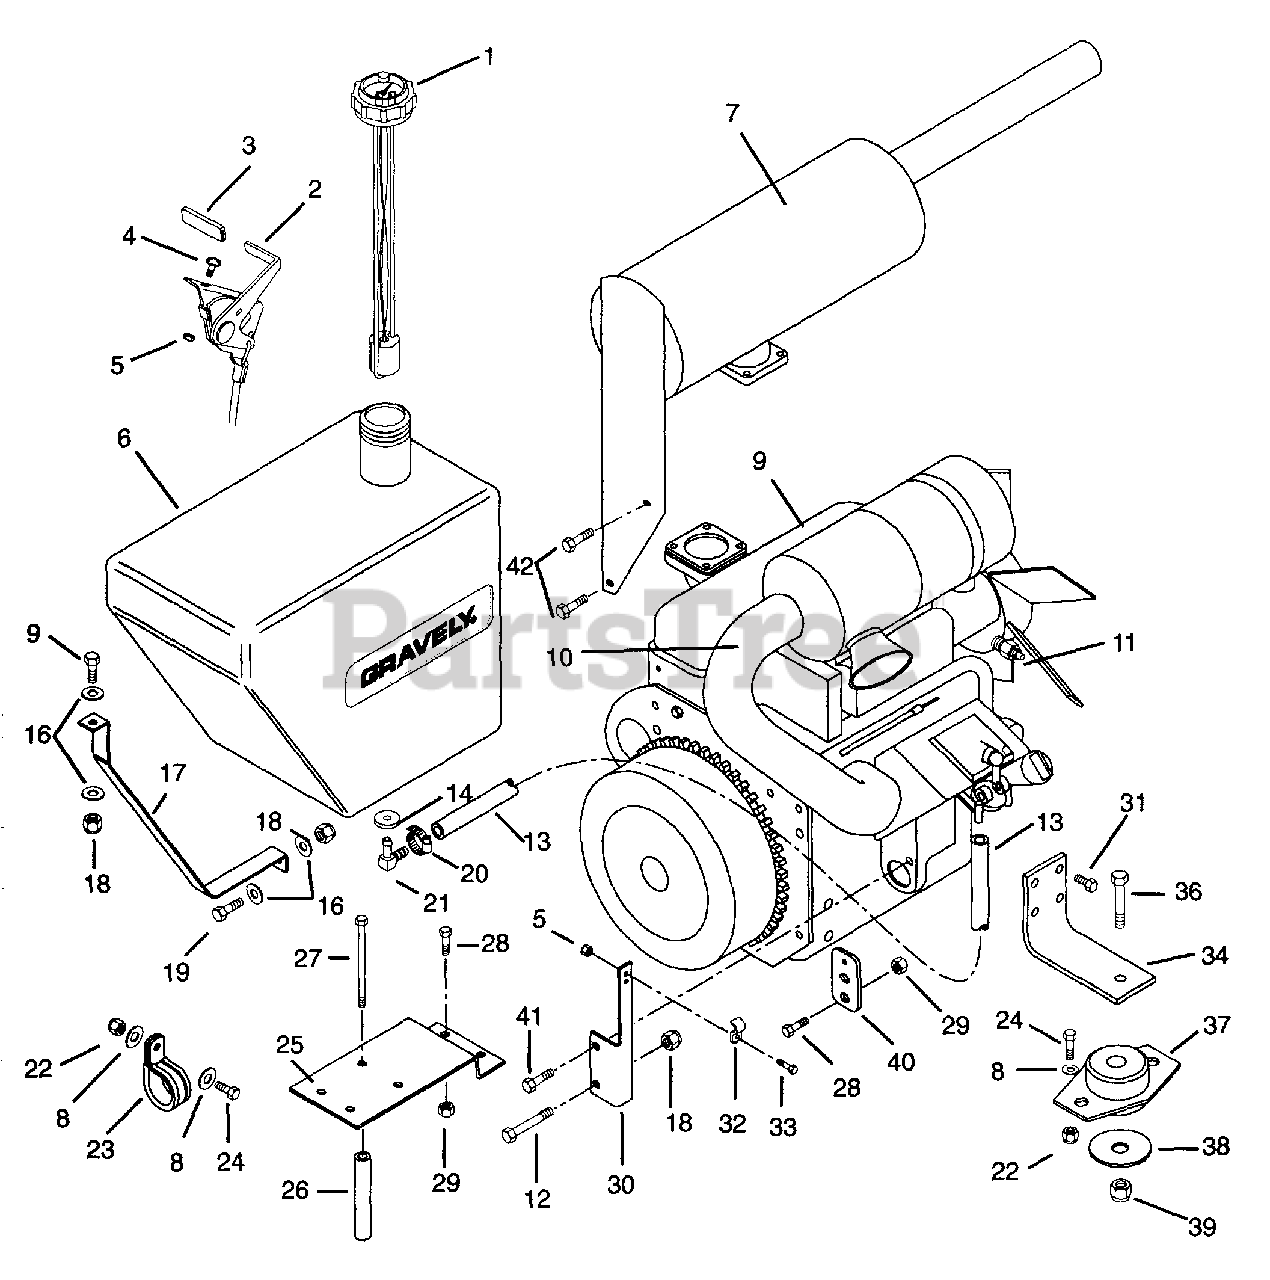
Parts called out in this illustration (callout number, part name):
1	Gauge, Fuel
2	Throttle Cable Assembly
4	Screw-Machine 10-24 x .50
5	Nut-Locking 10-24 w/Insert
6	Tank, Fuel
7	Muffler PM400, Kubota
8	Washer-Flat-Steel .406 x .812 x .065
9	Engine, Kubota V-1305-B1
10	Hose, Air Intake
11	Sender, Temperature
12	Bolt-Hex .31-18 x 1.25 Grade 5
13	Gas Line-Bulk
14	Bushing
15	Bolt-Hex .31-18 x 2.00 Grade 5
16	Washer-Flat-Steel .344 x .688 x .065
17	Strap, Gas Tank
18	Nut-Locking-Nylon .312-18 Grade 2
19	Bolt-Hex .31-18 x .75 Grade 5
20	Hose Clamp
21	Fitting-Tank 1.37 x .406
22	Nut-Locking-Center .38-16
23	Clamp, Steel 1.0
24	Bolt-Hex .375-16 x 1.00 Grade 5
25	Bracket, Air Cleaner Mount
26	Mount, Engine
27	Bolt-Hex M8 - 1.25 x 120
28	Bolt-Hex .25-20 x .75 Grade 5
29	Nut-Locking-Center .25-20
30	Bracket, Throttle Cable
31	Screw, Hex Head 10MM - 1.25 x 25
32	Clip Plated
33	Screw-Machine 10-24 x .75
34	Mount, Engine
36	Bolt-Hex .50-13 x 2.75 Grade 5
37	Mount, Engine Isolator
38	Washer-Snub-Steel .53 x 2.38 x .125
39	Nut-Locking-Nylon .50-13 Grade 5
40	Clip, Throttle Cable
41	Bolt-Hex M10 x 1.25 x 20
42	Bolt-Hex M8 x 1.25 x 25 Grade 8
